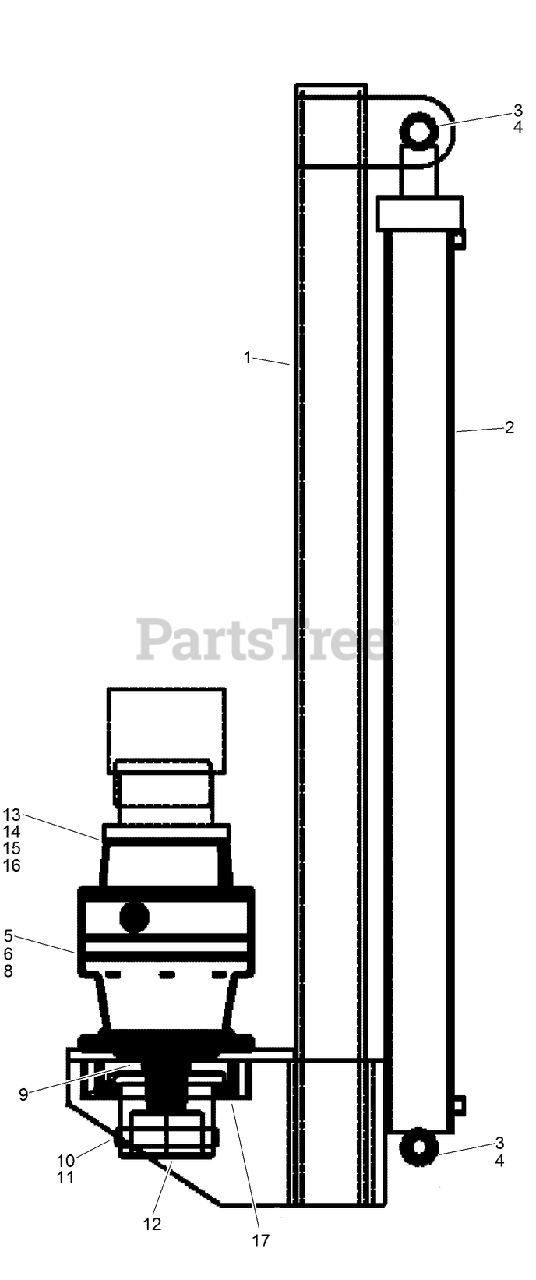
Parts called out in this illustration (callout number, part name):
1	WELDMENT - Stakedown
2	HYD CYLINDER ASM
3	PIN-BAR
4	PIN - Cotter, 1/8 inch Diameter x 2 inch Long
5	PLANETARY GEARBOX ASM
6	SCREW, METRIC FLANGE w/BODY - M8 x 80
8	NUT-TORQUE, PREVAILING
9	SPACER - Gearbox
10	PIN-BAR, AUGER COUPLER
11	RING-RETAINING, E-TYPE
12	COUPLER - Stakedown Auger Drive
13	HYD MOTOR ASM
14	SCREW - Cap, Hex Head, 5/16 - 18 x 1-1/4 inch Long
15	SEAL - O-Ring
16	SCREW - Cap, Hex Head, M12 x 1/75 x 35 MM Long
17	RETAINER - Stakedown Auger Drive
